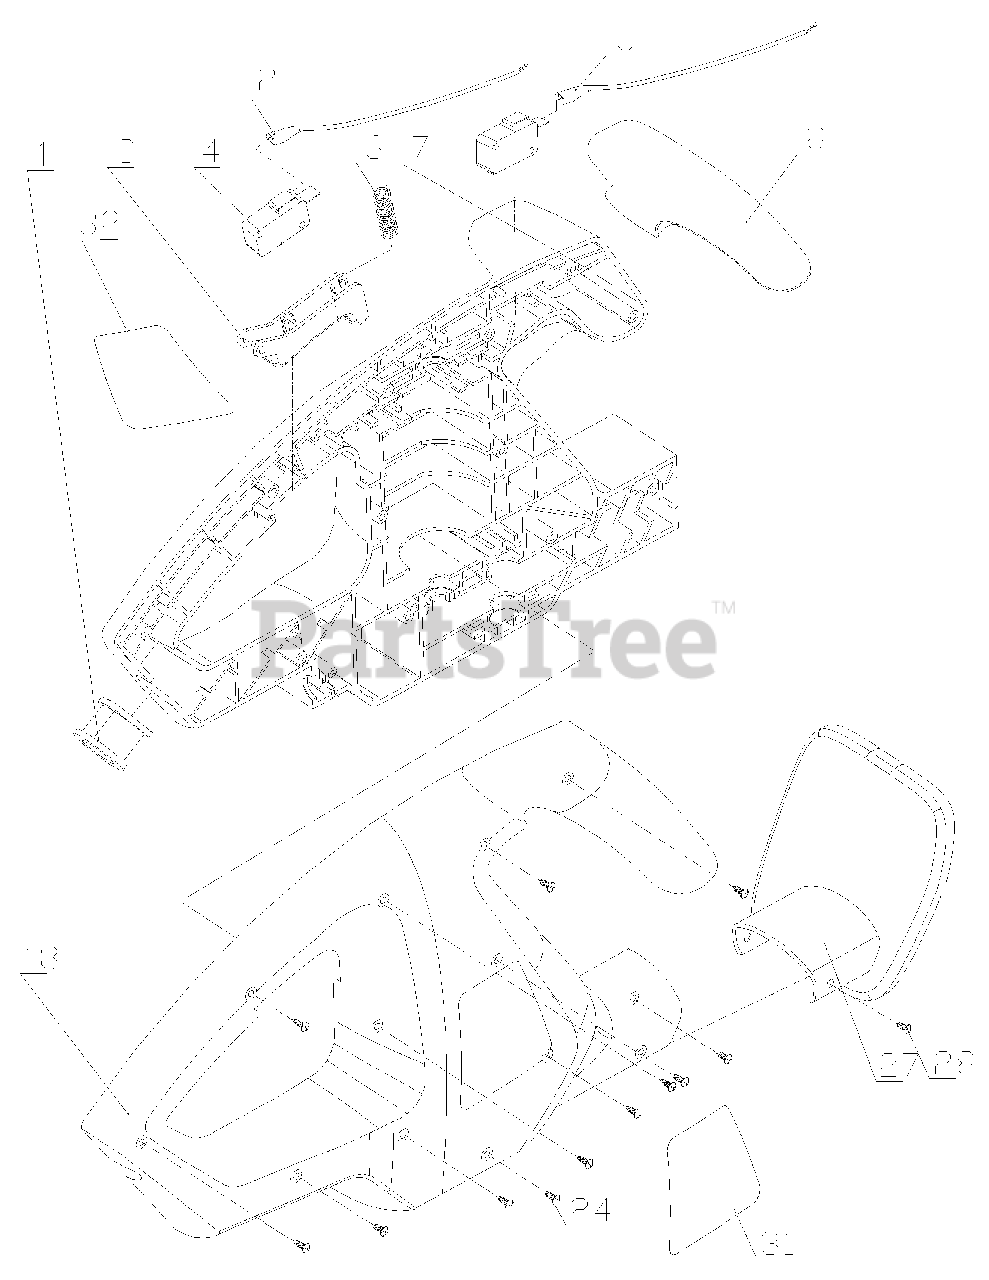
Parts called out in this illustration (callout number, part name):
7	HOUSING (L)
9	FIELD ASS'Y
12	20" BLADE
14	ECCENTRIC SHAFT
15	OUTPUT SHAFT
17	BRUSH HOLDER
18	HOUSING (R)
19	TERMINAL BLOCK
21	STRAIN RELIEF
22	CORD GUARD
23	POWER CORD
25	BLADE COVER
31	LABEL (R)
32	LABEL (L)
